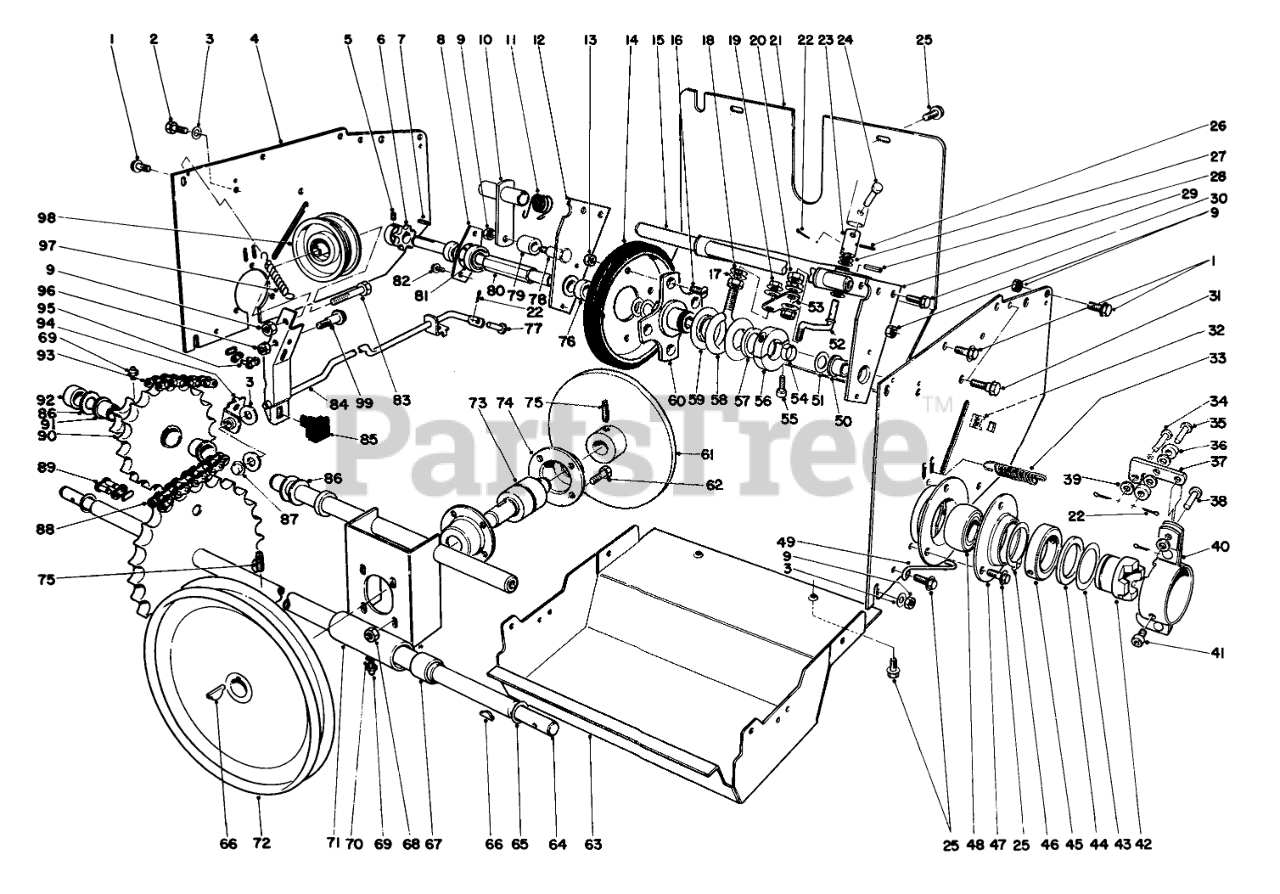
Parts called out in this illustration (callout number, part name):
1	SCREW-HH
2	SCREW-HHFTF
3	WASHER-FLAT
4	Side Plate Drive
5	SCREW-HSH
6	SPROCKET
8	BEARING CUP
9	NUT-LOCK, NI
10	CHAIN TENSION ARM WA
11	TORSION SPRING
12	HEX SHAFT MOUNT R
13	NUT-LOCK, NI
14	FRICTION WHEEL
15	Bracket Dead Shaft
16	5/16-18X5/8 FLT HD MS
17	Washer
18	WASHER-SPRING
19	NUT-LOCK, FLANGE
20	NUT-LOCK
21	REAR COVER R
22	PIN-COTTER
23	U JOINT TUBE
24	CLEVIS PIN
25	SCREW-HWH
26	PIN-SPRING
27	Clevis Pin
28	PIN-ROLL
29	Hex Shaft Mounting (Incl. Ref. #50)
30	SCREW-HWHTF
31	SHOULDER SCREW
32	Retained Nut
33	EXTENSION SPRING
34	PIN-CLEVIS
35	PIN-CLEVIS
36	CLUTCH ROLLER
37	CLUTCH CAM ARM
38	PIN-CLEVIS
39	WASHER-FLAT
40	CLUTCH MT BRKT ASM
41	SCREW-HSH
42	WHEEL CLUTCH
43	THRUST WASHER
44	THRUST BEARING
45	CLUTCH MOUNT COLLAR
46	RING-RETAINING, EXTERNAL
47	BEARING FLANGE
48	BEARING
49	CLUTCH RETAINER
50	BUSHING
51	WASHER-FLAT
52	CONNECTION ROD
53	SHIFT ROD PIVOT
54	SPLIT SPACER
55	SCREW-HSH
56	ColIar
57	WASHER-THRUST
58	SLIDER RING COLLAR
59	SLIDER RING
60	TRACTION DISC HUB
61	Friction Plate
62	SCREW-HH
63	LOWER SHIELD R
64	AXLE SHAFT WA
65	WASHER
66	KEY-WOODRUFF
67	Bearing
68	NUT-KEPS
69	FITTING-GREASE
70	WASHER-LOCK
71	Bulkhead (Incl. Ref. #67)
72	Pulley
73	Friction Plate Shaft
74	HOUSING BEARING
75	Set Screw
76	SPACER
77	PIN-CLEVIS
78	SHOULDER BOLT
79	CHAIN TENSION ROLLER
80	FRICTION WHEEL SHAFT
81	BEARING
82	SCREW
83	SCREW-HH
84	Auger Brake Assembly (Incl. Ref. #85)
85	Brake Pad
86	WASHER-THRUST
87	PUSH NUT
88	Lower Chain (Incl. Ref. #89)
89	LINK-CHAIN
90	Sprocket (Incl. Ref. #69 & 91)
91	3/4ID X 3/4LG BSHG
92	SPACER-IDLER
93	Upper Chain (Incl. Ref. #95)
94	Bracket-Clutch
95	LINK-CONNECTING
96	NUT-LOCK, CONE
97	SPRING
98	Idler Pulley
99	BOLT-SHOULDER
